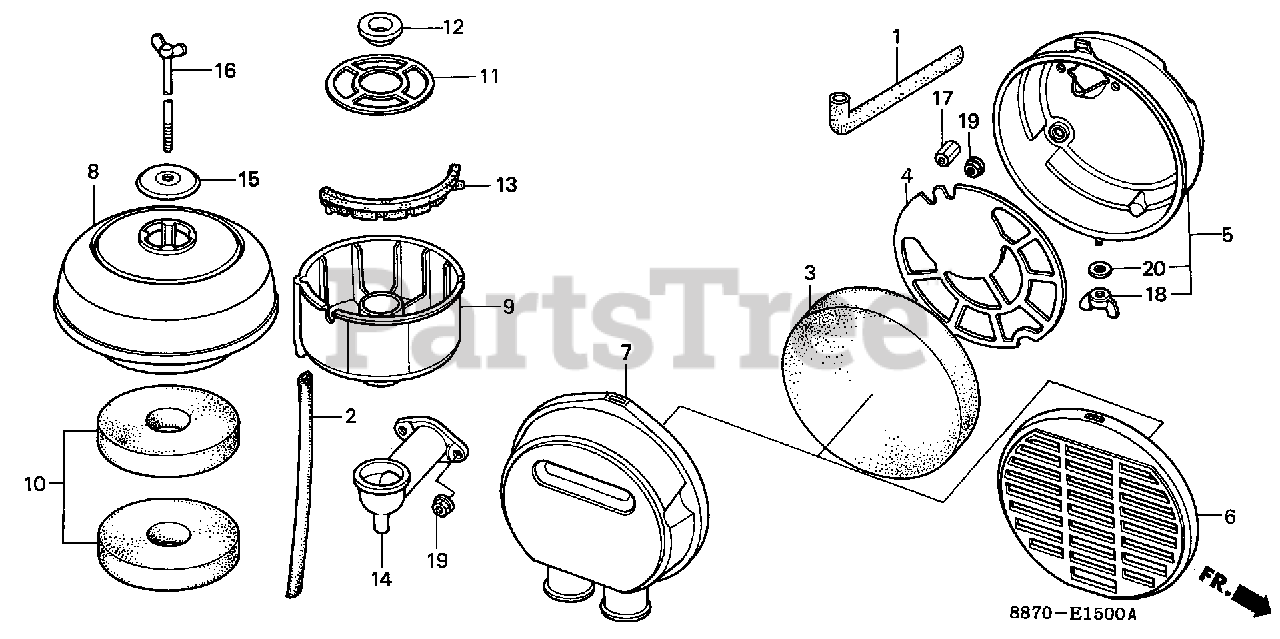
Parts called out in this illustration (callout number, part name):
1	TUBE, BREATHER
3	ELEMENT, AIR CLEANER
4	GRID, AIR CLEANER
5	HOUSING, AIR CLEANER
6	COVER, AIR CLEANER
7	COVER, AIR CLEANER
17	NUT (6X15)
18	NUT, TOOL BOX SETTING
19	NUT, FLANGE (6MM)
20	WASHER, PLAIN (6MM)
